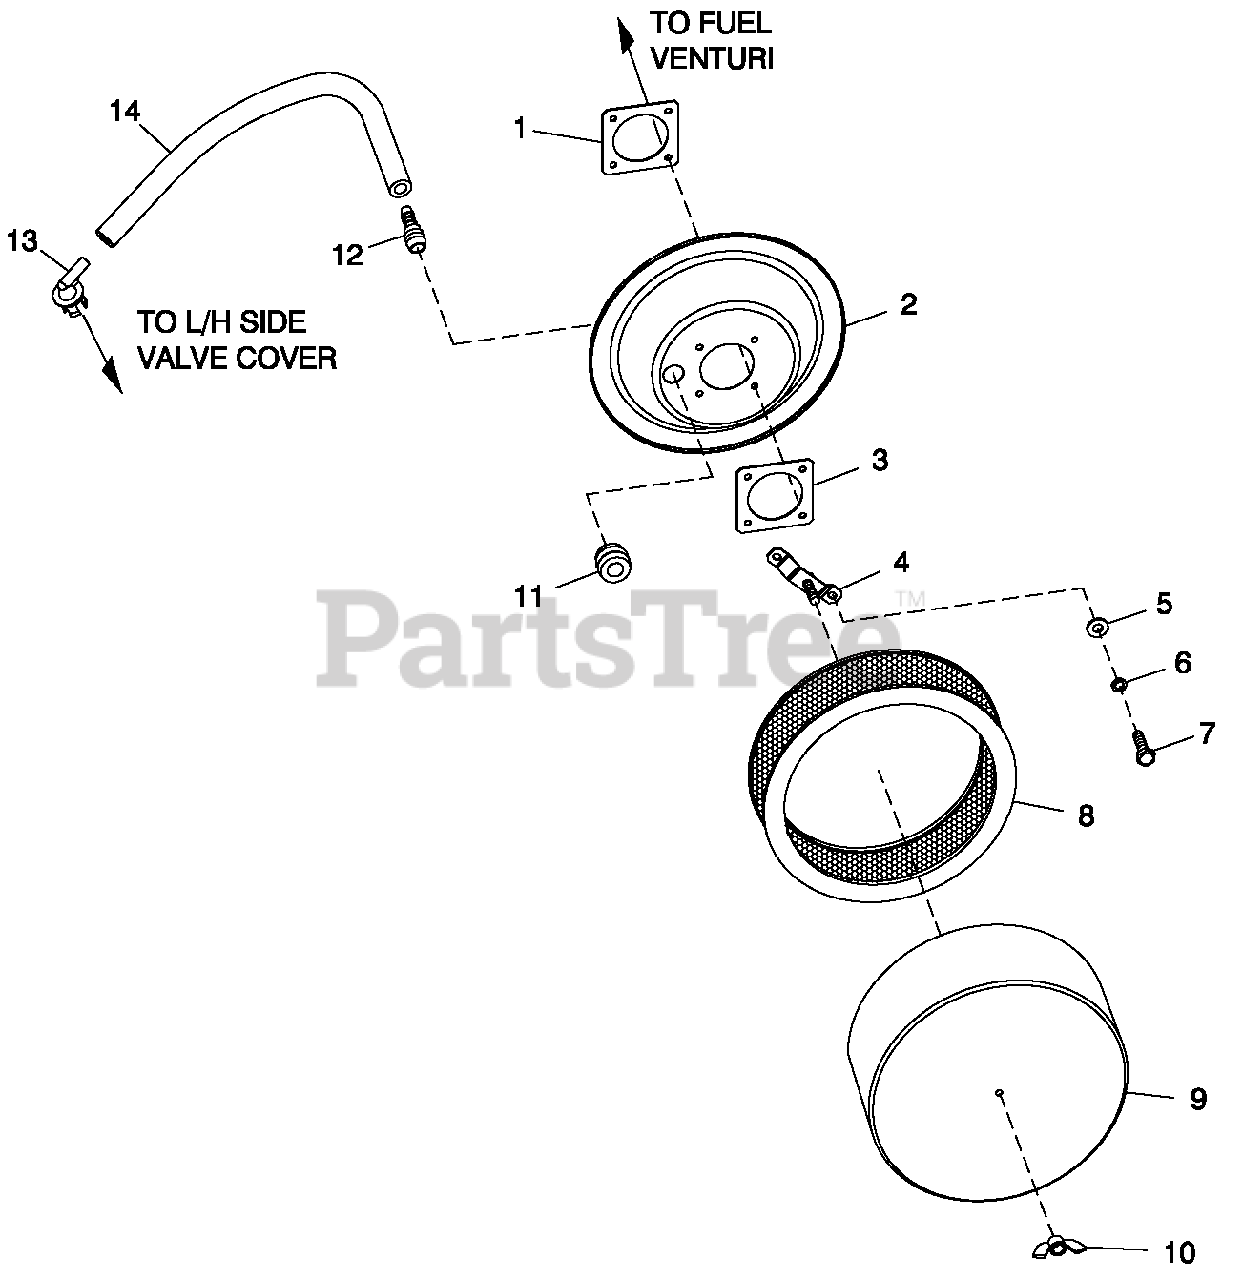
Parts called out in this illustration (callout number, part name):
1	GASKET, MIXER BODY
2	BASE PLATE AIR CLEANER
3	TOP PLATE VENT URI
4	HOLD DOWN AIR CLEANER
5	WASHER FLAT M6
6	WASHER LOCK M6-1/4
7	SCREW HHC M6-1.0X 16 G8.8
8	ELEMENT AIR FILTER
9	PLATE, AIR CLEANER TOP
10	N UT WING 1/4-20 NYLK
11	GROMMET 15.87X31.75X11
12	HOSE BARB REDUCER 5/8"-3/8"ID
13	ELBOW, CRANKCASE BRTHR 3.0L G3
14	HOSE 3/8 ID SINGLE BRAID (13" LG)
